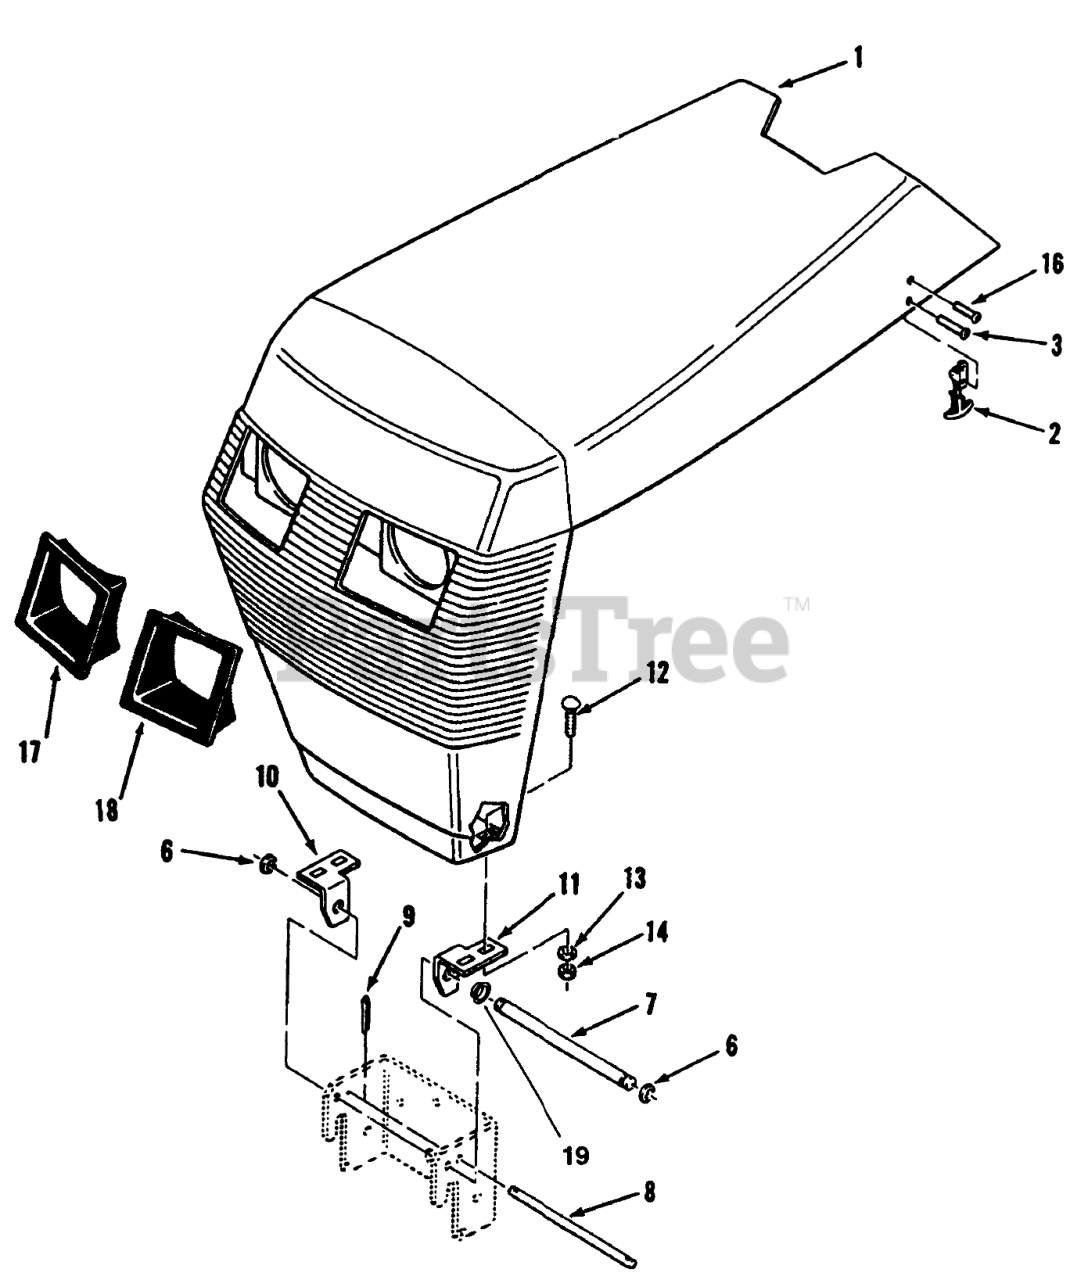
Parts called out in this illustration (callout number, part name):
1	SERV.ASSY-HOOD & PKG
2	LATCH-FLEX BLK ASS'Y
3	RIVET-POP
6	RING-RETAINING
7	ROD-GRILL PIVOT
8	ROD-HOOD STOP
9	Cotter Pin
10	BRACKET-GRILL, R H
11	BRACKET-GRILL, LH
12	SCREW-CARR
13	WASHER-FLAT
14	NUT-HEX
16	NUT-LOCK, NI
17	BEZEL-HEADLIGHT, RH
18	BEZEL-HEADLIGHT, LH
19	NYLINER BUSHING
